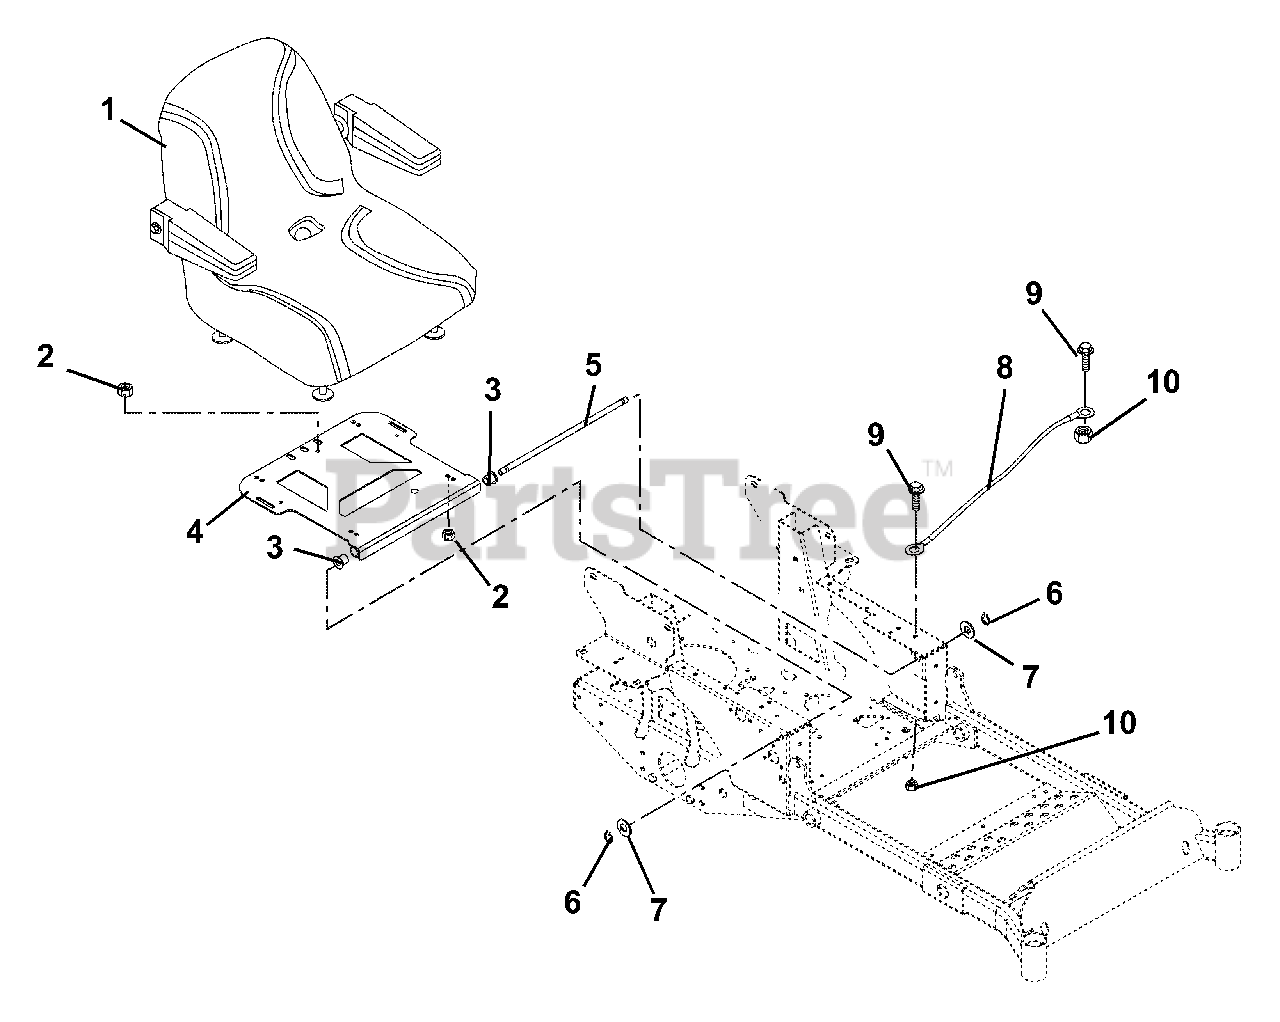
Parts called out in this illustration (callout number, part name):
1	SEAT, TS2800 MICHIGAN W/ARM.
2	@NUT-LK-TOP-FLG .31-18 YWZC
3	BSHG-FLG .515X.750X.745X1.00NY
4	WMT, SEAT PIVOT MOUNT
5	ROD, SEAT FRAME PIVOT
6	RG-RTNG-EXT .500X.050 (SNAP)
7	@WSHR-FL-STL.531X1.06X.095YWZC
8	CBL,HOOD
9	@BLT-HEX .25-20X.75 GR5 YWZC
10	@NUT-LK-TOP-FLG .25-20 YWZC
